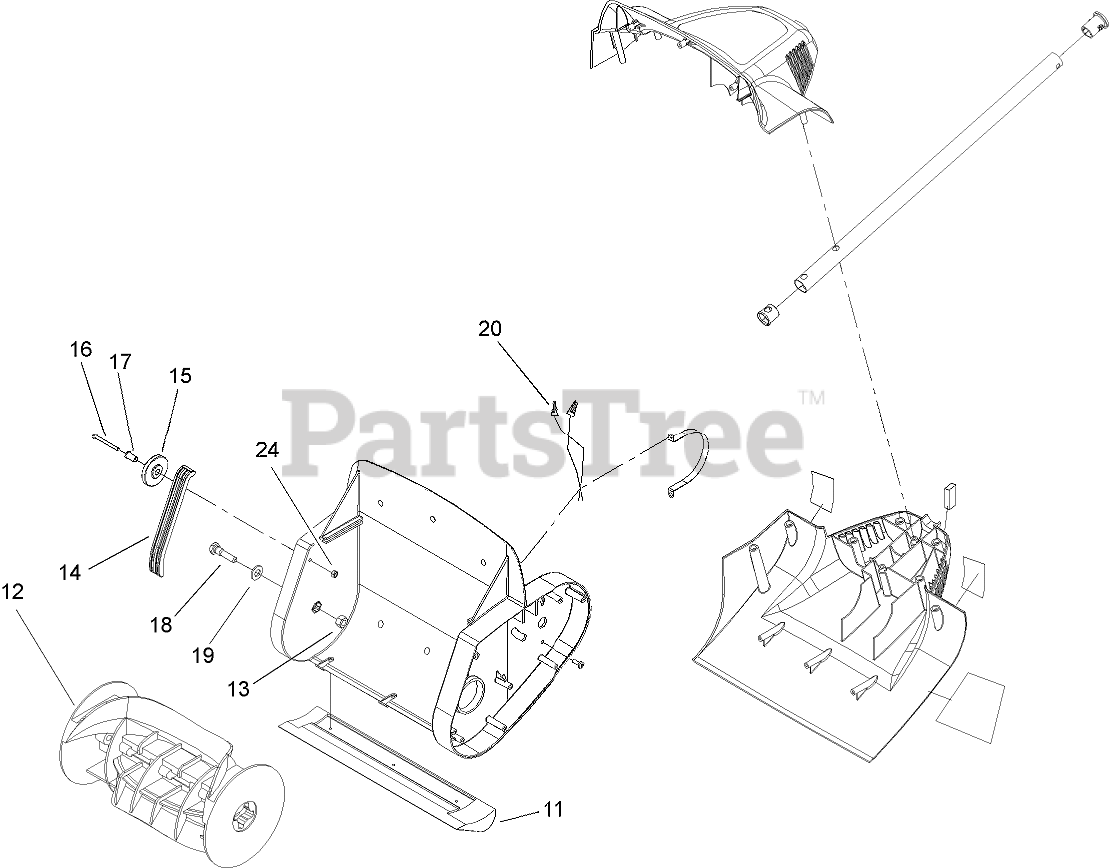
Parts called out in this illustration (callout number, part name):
11	SCRAPER-SNOW
12	ROTOR-SNOW
13	NUT-LOCK
14	SCRAPER-RIGHT, SWEEP
15	WHEEL-SWEEP
16	SCREW-PPH
17	BUSHING-WHEEL
18	PIN-ROTOR
19	WASHER-FLAT
20	CONNECTOR-NUT, WIRE
24	NUT-LOCK
